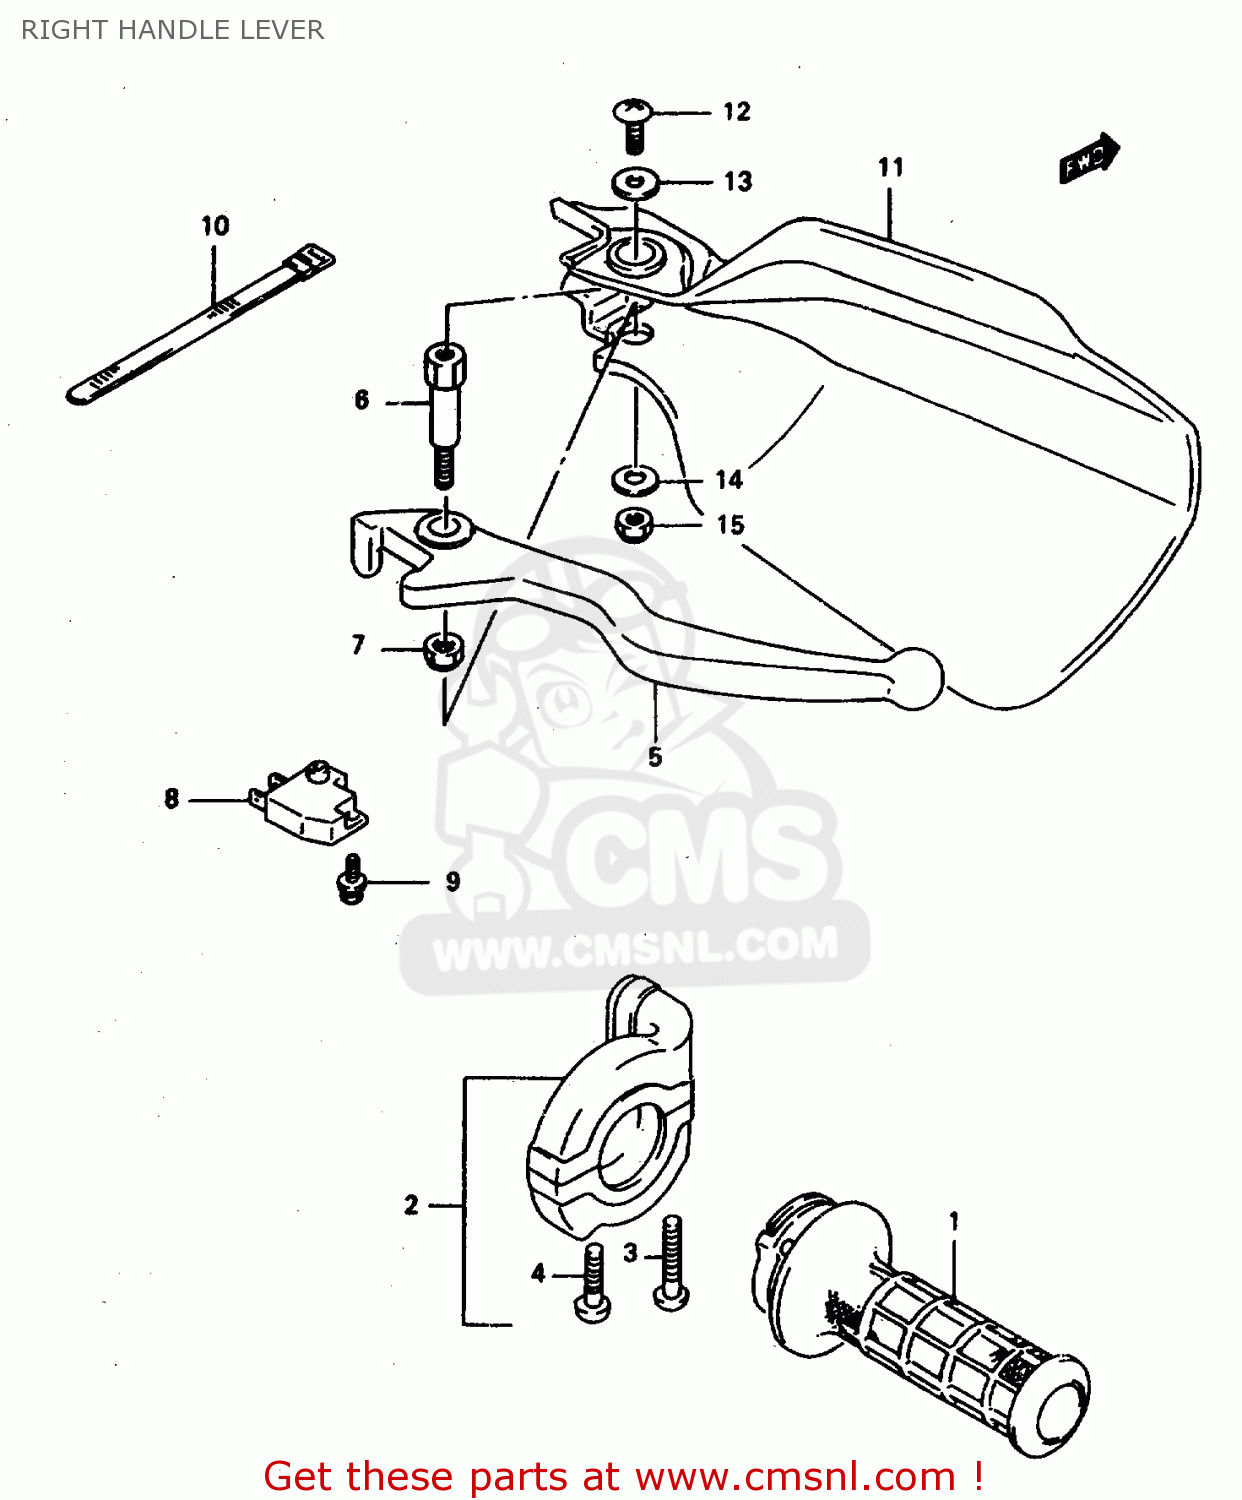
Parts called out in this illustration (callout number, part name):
1	GRIP,THROTTLE
2	CASE ASSY,THROTTLE
3	SCREW(5X25)
4	SCREW
5	LEVER,BRAKE
6	BOLT,BRAKE LEVER PIVOT
7	NUT
8	SWITCH ASSEMBLY,STOP
9	SCREW
10	CLAMP(L:120)
11	COVER,KNUCKLE,RIGHT
12	SCREW
13	WASHER (5.5X16X1.2)
14	WASHER (6.5X17X1.6)
15	NUT 6MM
